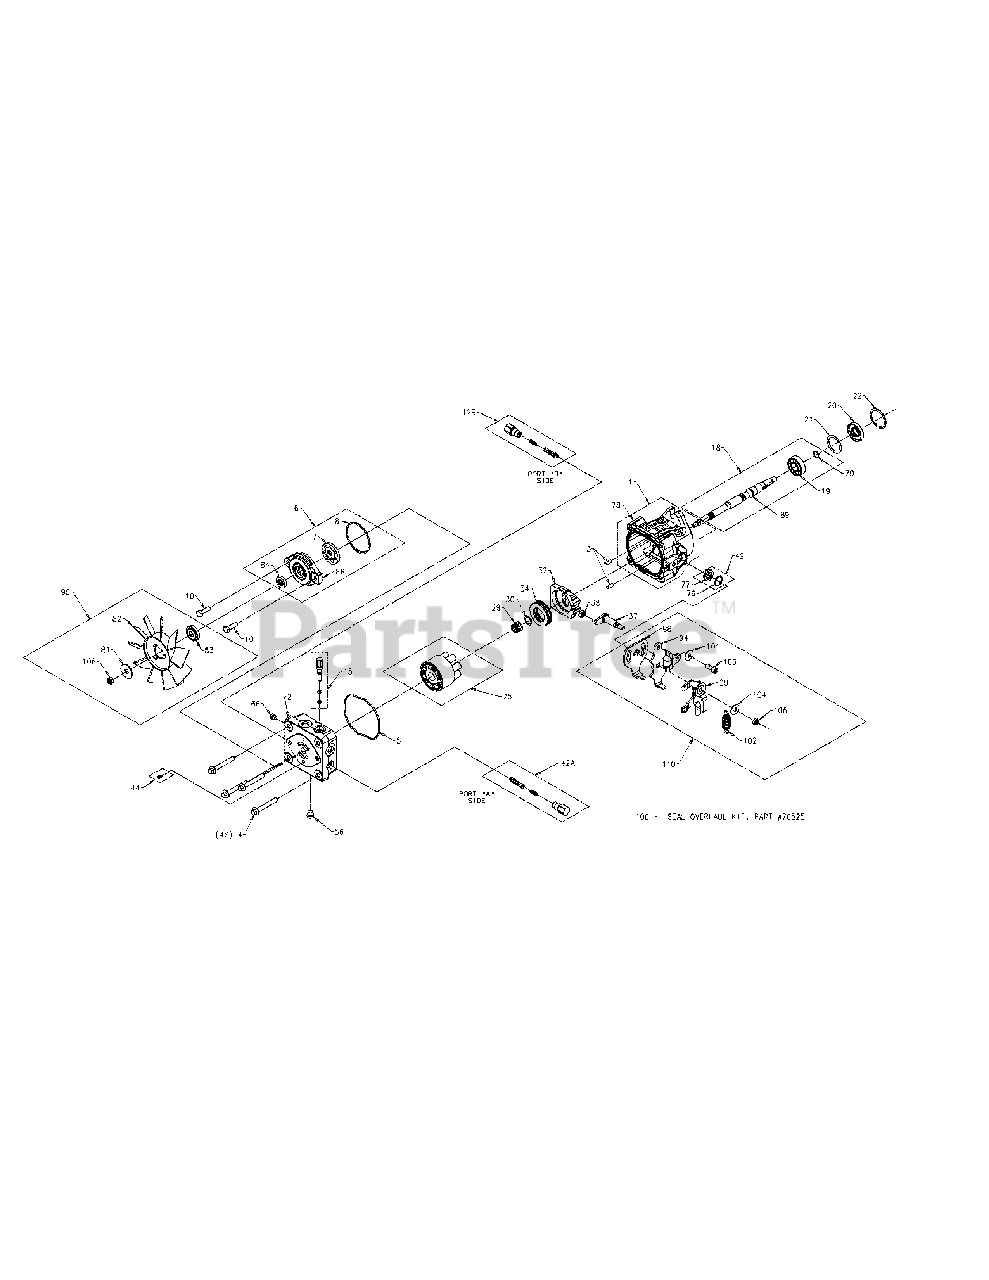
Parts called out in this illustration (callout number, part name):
1	Kit, Housing
2	Kit, Endcap
3	Straight Headless Pin
4	Hex Flange Bolt M8-1.25 x 60mm Long
5	Housing, O-Ring
5	O-Ring, Housing
6	Kit, Charge Pump (STD CHG .19 ci/rev, Thru)
7	Gerotor
8	O-Ring
10	Screw, 5/16-18 x 1.00 Long
15	Kit, Bypass Valve
18	Kit, Pump Shaft (15mm Tapered Keyed Thru)
20	Lip Seal 17 x 40 x 7 PTC
22	Retaining Ring
22	Ring, Retaining
25	Cylinder Block Kit
29	Block Spring
30	Block Thrust Washer
34	Ball Thrust Bearing
37	Arm, Trunnion Tapered Square
42A	Kit, Shock Valve (200 Bar, .031 Orifice)
42B	Kit, Shock Valve (200 Bar, .031 Orifice)
44	Charge Relief Kit, (1/4 Plastic Ball & 2000029 Spring)
49	Trunnion Seal / Retainer Kit
56	Plug - 7/16-18 Steel (Diagnostic)
66	Plug 9/16-18 (Metal)
76	Ring, Retaining
78	Housing, Pump
79	Ring, Ret. Wire .561 I.D.
82	Fan, 6", 10 Blade
83	Fan Hub
84	Seal
86	Housing, Charge Pump
89	Shaft, Input Tapered Keyed
90	Kit, Fan
94	Arm, Control
98	Arm, RTN
99	Assembly, RTN Bi-Directional
100	Overhaul Seal Kit
102	Spring, Extension (STD)
103	Screw, 5/16-24 x .75 (Patch)
104	Washer
110	Kit, RTN
